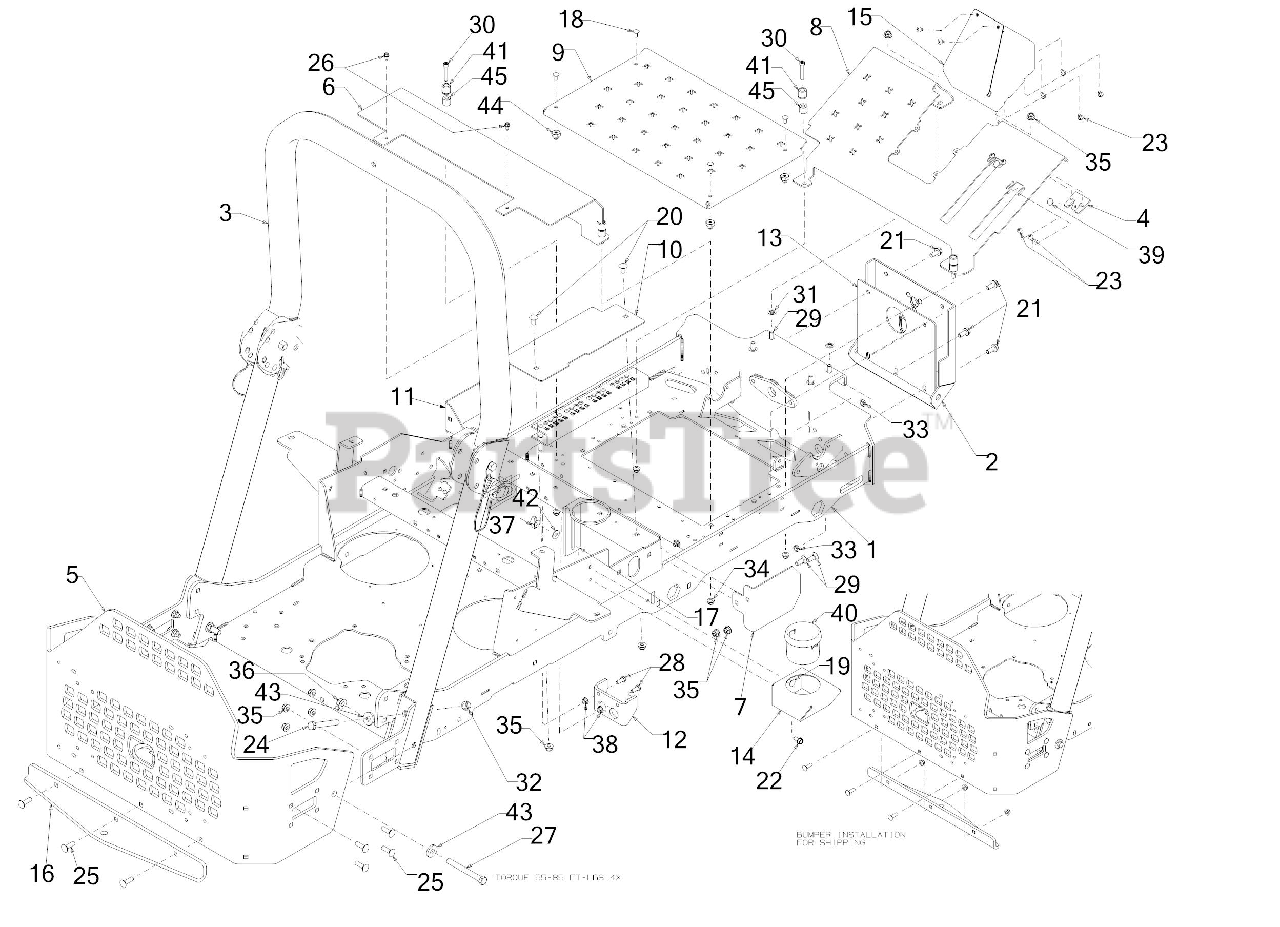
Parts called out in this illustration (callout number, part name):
3	FOLDING ROPS ASSEMBLY
18	CARRIAGE BOLT 1/4-20 x .62
19	CARRIAGE BOLT 5/16-18 x 1.00
20	CARRIAGE BOLT 3/8-16 x .750 GR5
21	SCREW 3/8-16 x .875 GR5
22	SCREW 5/16-18 x .750
23	SCREW 1/4-20 x .5
24	SCREW 1/2-20 x 3.50 GR5
25	CARRIAGE BOLT 3/8-16 X1.25 GR5
26	SCREW 1/4-20 X.500
27	SCREW 1/2-13 x 4.5 GR 5
28	SCREW 5/16-18 x .75 GR5
29	CARRIAGE BOLT 3/8-16 x 1.00 GR5
30	SCREW 5/16-18X1.75 GR5
32	HEX NUT
33	JAM LOCK NUT
34	FLANGE LOCK NUT 5/16-18
37	WING NUT 5/16-18
38	FLANGE NUT
39	RATCHET CLIP
41	RADIAL BUMPER
42	FLAT WASHER
43	FLAT WASHER .531 x 1.25 x .181
44	SHOULDER SPACER
